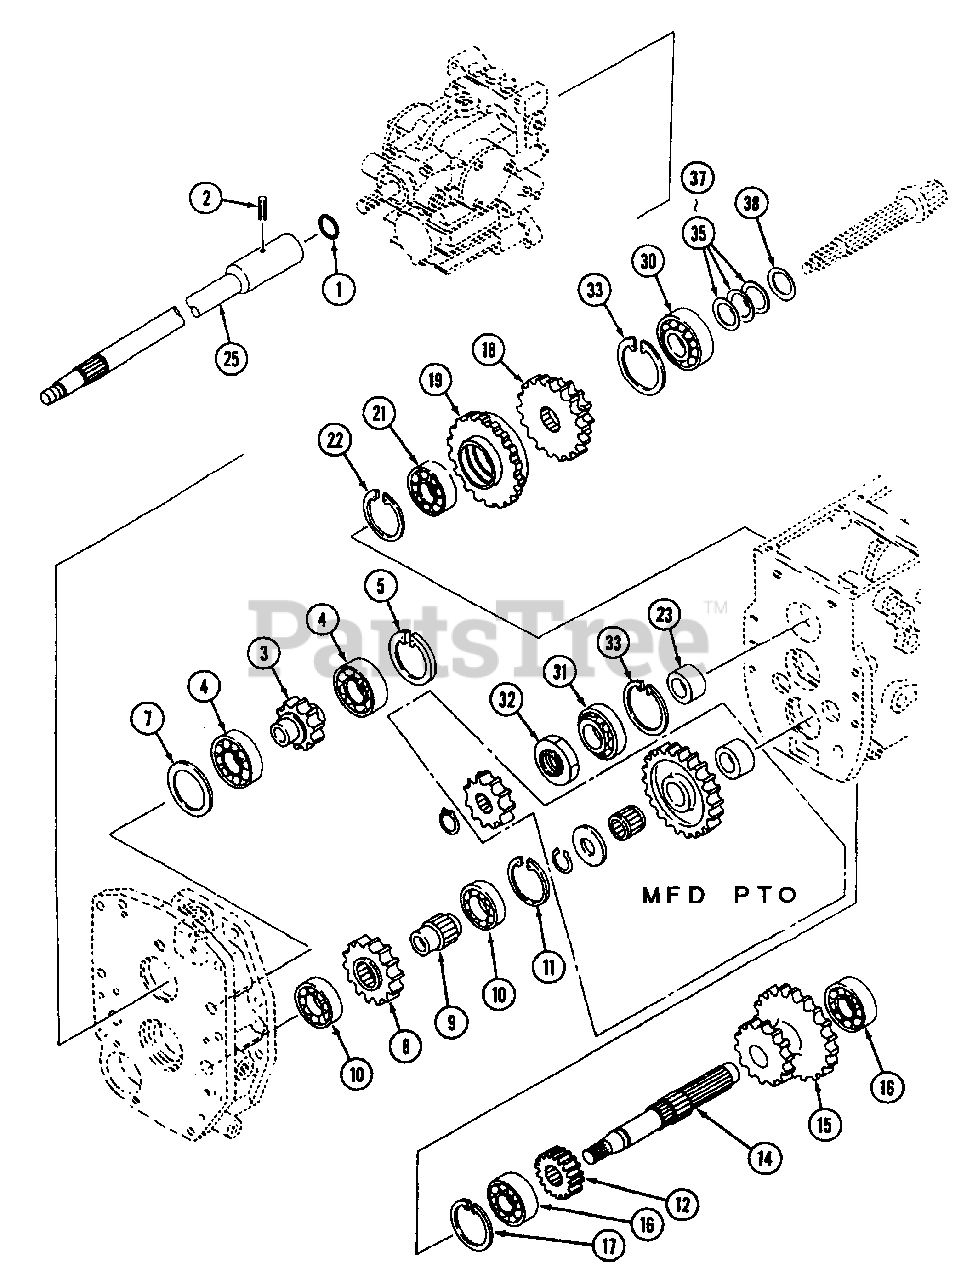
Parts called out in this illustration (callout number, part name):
14	Shaft, Sub Change
15	Gear, 26T-34T
25	Shaft, Main
